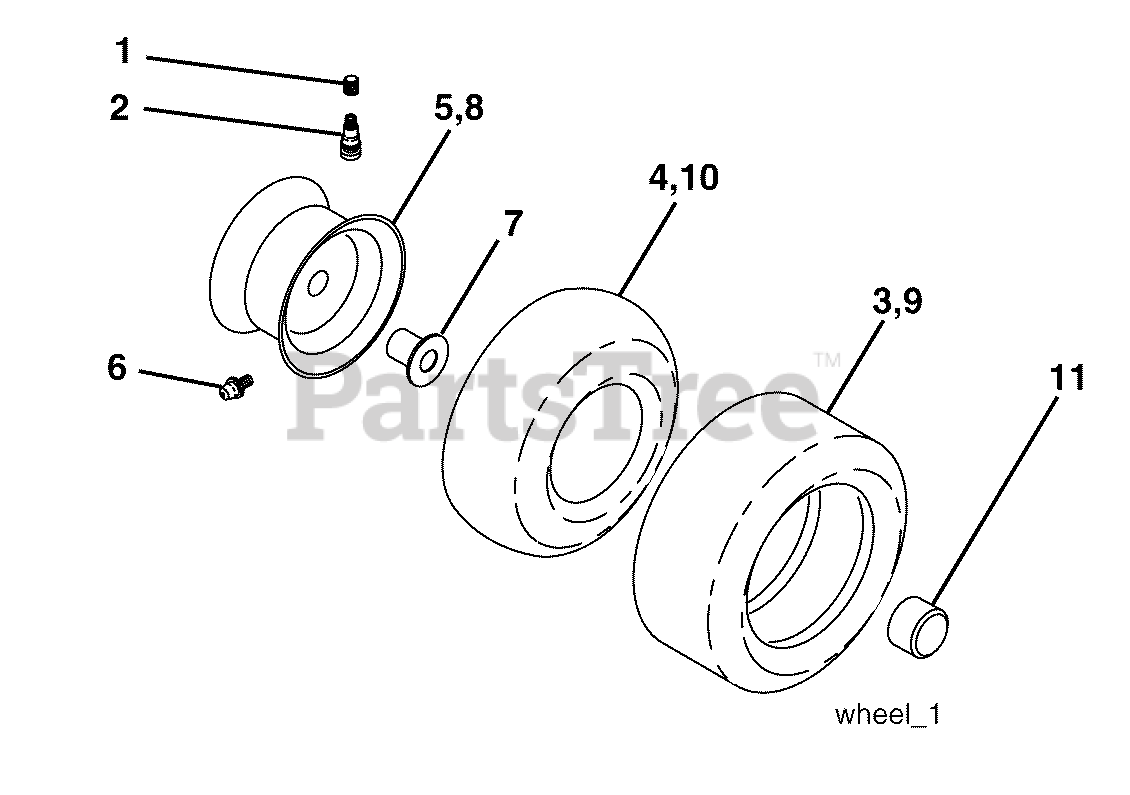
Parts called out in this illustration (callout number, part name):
1	Cap Valve Tire
2	Stem Valve
3	Tire F Ts 15 x 6 0 - 6 Service
4	Tube Front
5	Rim Asm 6"front Silver Service
6	Fitting Grease
7	Bearing Flange
8	Rim Asm 8"rear Silver Service
9	Tire R Ts 20 x 8-8 C Service
10	Tube Rear
11	Cap Axle Blk 1 50 x 1 00
